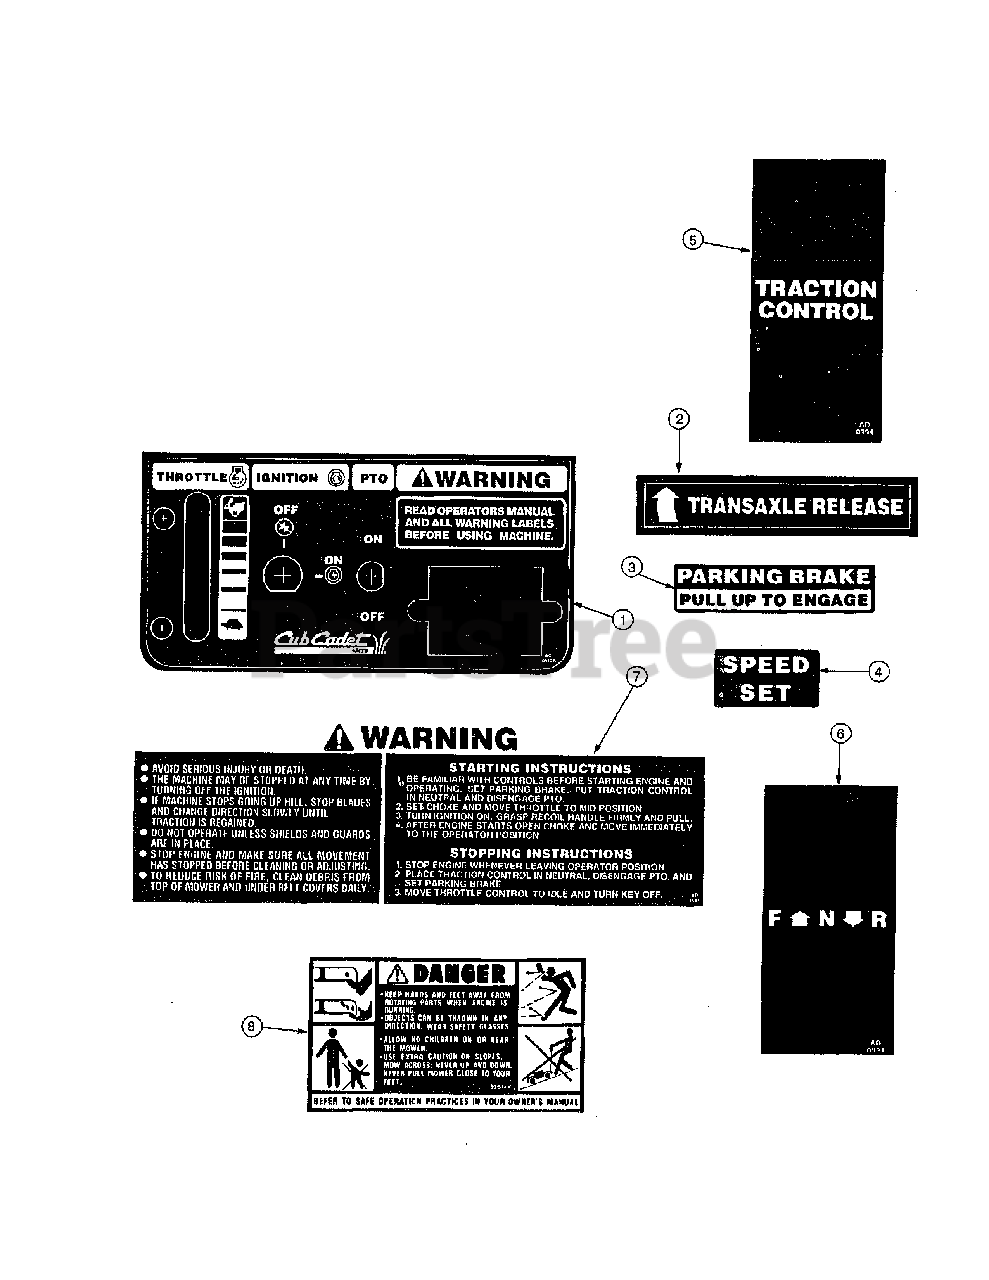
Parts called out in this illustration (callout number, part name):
1	Graphic, Control Panel
2	Graphic, Transaxle Release
3	Graphic, Park Brake
4	Graphic, Speed Set
5	Graphic, Traction Control
6	Graphic, F-N-R
7	Graphic, Warning
8	Graphic, Danger
